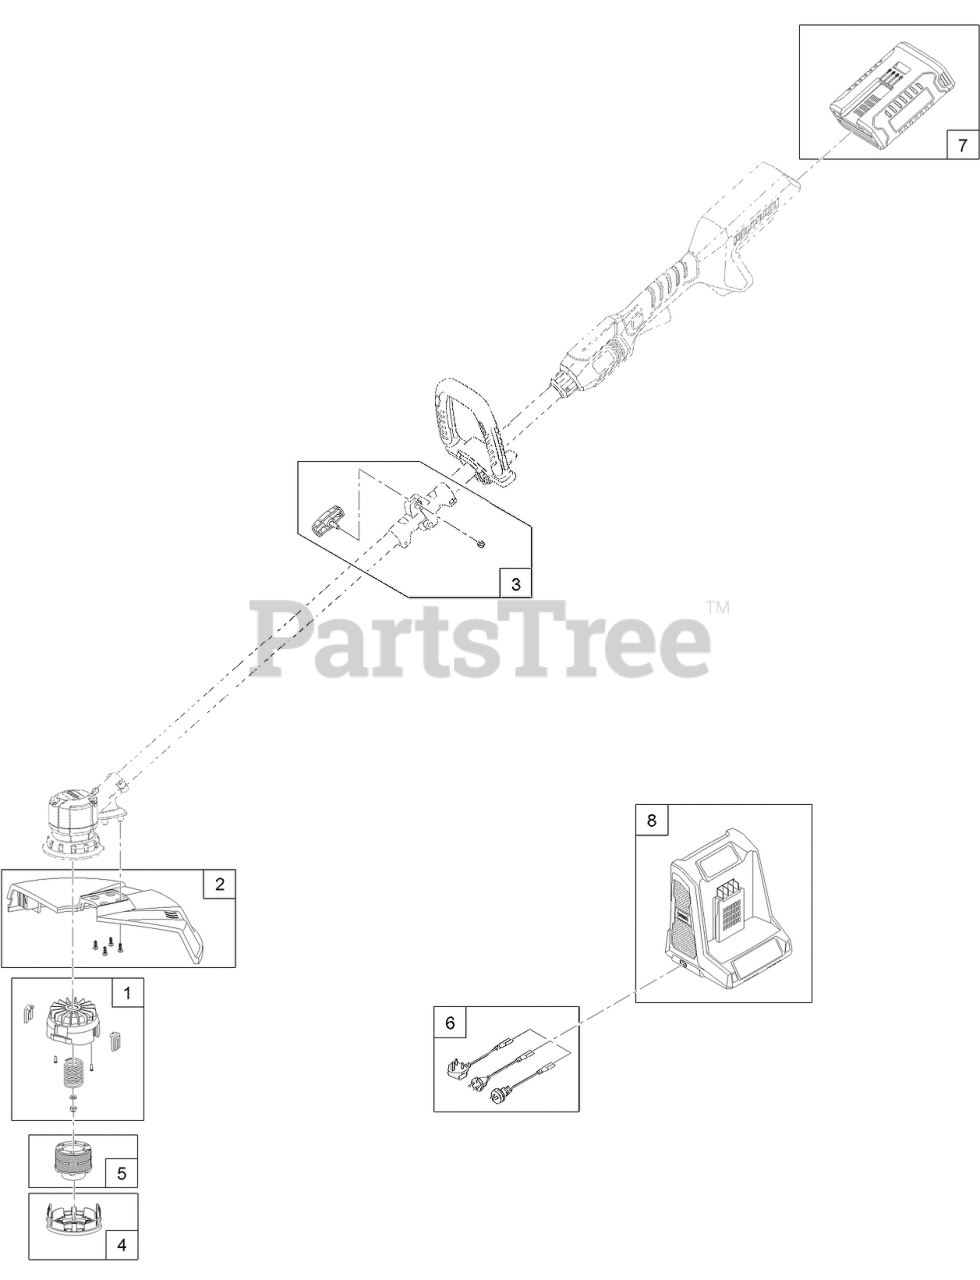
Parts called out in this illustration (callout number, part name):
1	HEAD-FEED, BUMP
2	SHIELD-GRASS
3	SHAFT CONNECTION HARDWARE KIT
4	RETAINER-CAP, SPOOL
5	3-PACK DUAL-LINE TRIMMER SPOOL
6	CORD SET
7	BATTERY-40V MAX
8	CHARGER-BATTERY, 40V MAX
